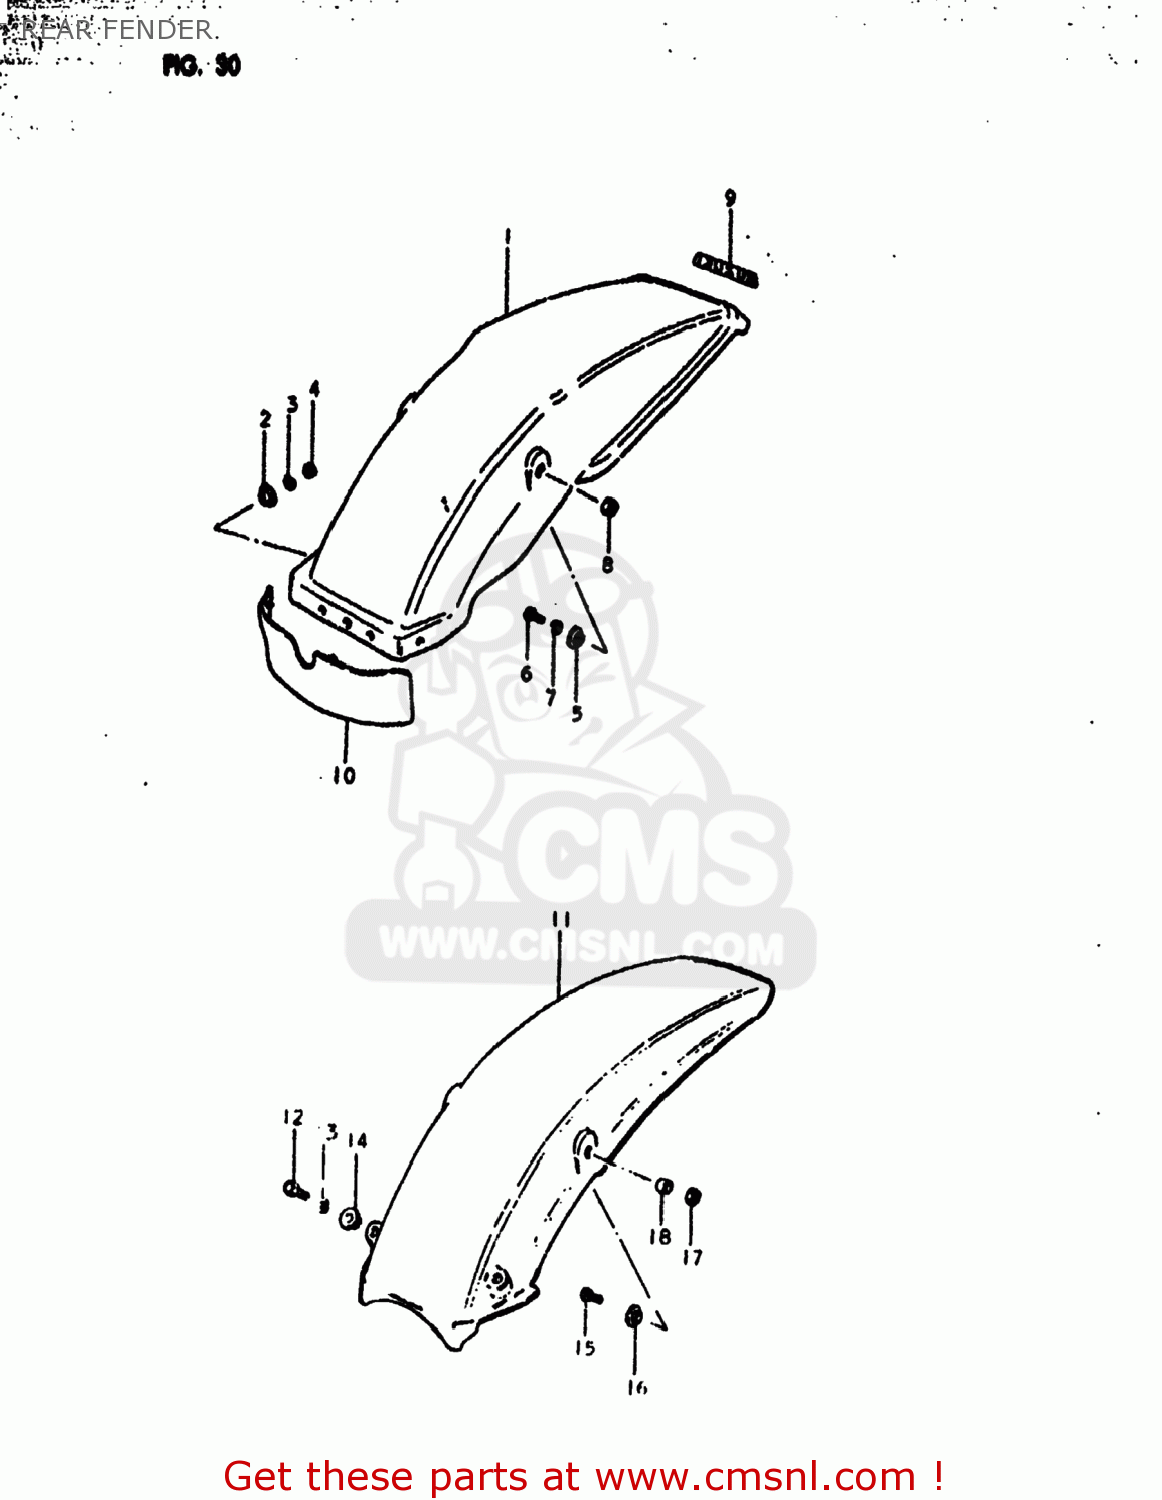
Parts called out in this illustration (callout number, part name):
1	FENDER,REAR
2	WASHER
3	LOCK WASHER
4	NUT
5	WASHER
6	BOLT, UPPER
7	LOCK WASHER
8	NUT 6MM
9	EMBLEM,FRONT FENDER
10	MUD GUARD,REAR FENDER
11	FENDER,REAR
12	BOLT
13	LOCK WASHER
14	WASHER
15	SCREW
16	WASHER (6.5X20X1.2)
17	NUT 6MM
